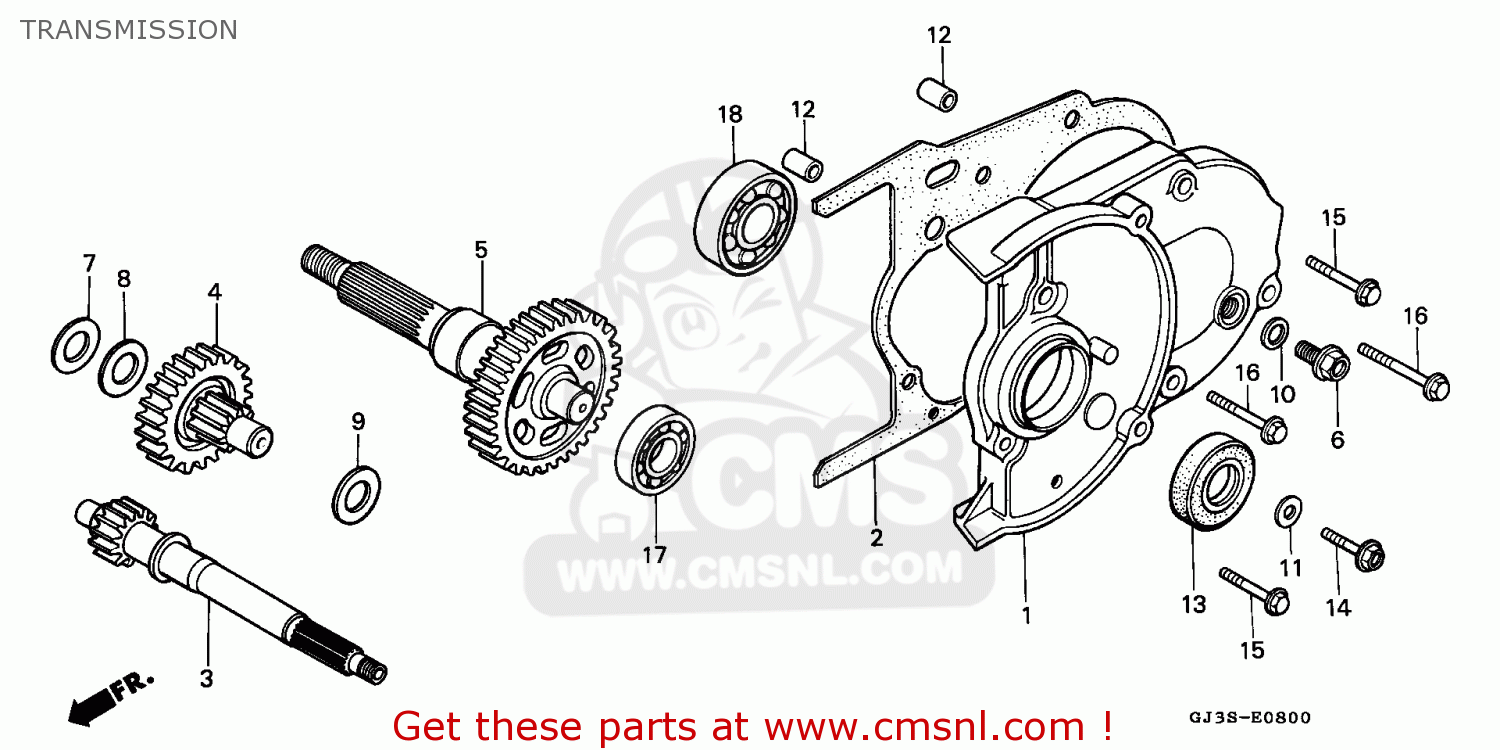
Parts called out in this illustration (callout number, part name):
1	COVER,MISSION
2	GASKET,MISSION CO (NAS)
3	SHAFT,DRIVE
4	SHAFT COUNTER
5	GEAR COMP.,FINAL
6	CHECK BOLT,OIL LE
7	WASHER,SIDE,14MM
8	WASHER,14MM
9	WASHER,14MM
10	WASHER, 12MM
11	WASHER, 10.2M/M
12	PIN,DOWEL,10X14
13	OIL SEAL.,17X30X6
14	BOLT,FLANGE,6X12
15	BOLT,FLANGE,6X28
16	BOLT,FLANGE,6X35
17	B/BRG RAD N/COM
18	B/BRG RAD N/COM
